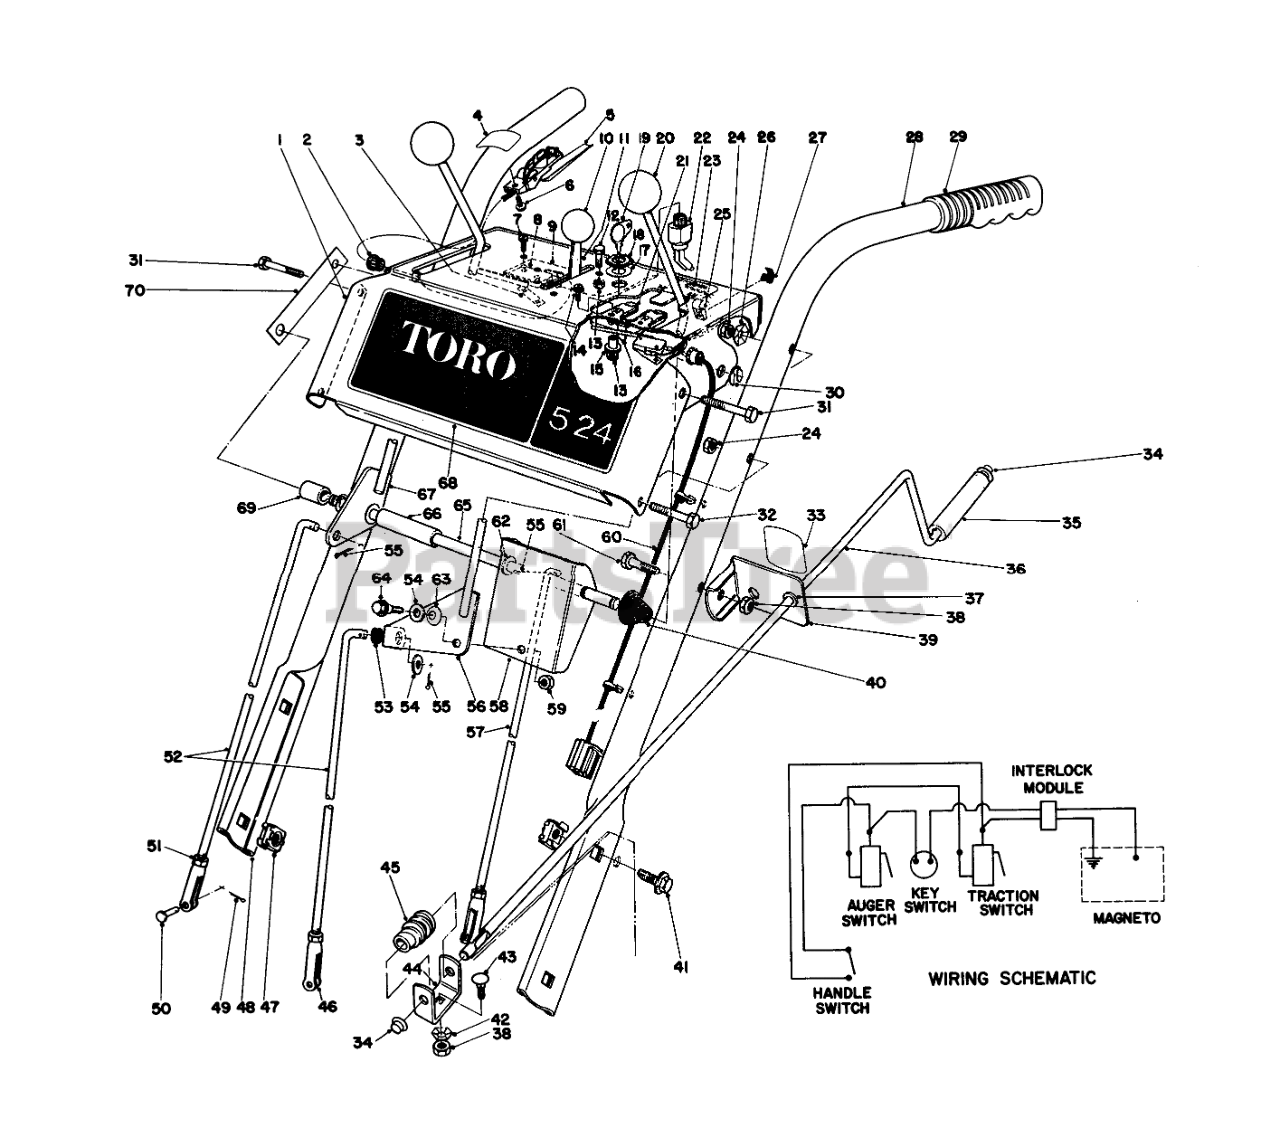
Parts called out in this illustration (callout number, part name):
1	ESCUTCHEON PLT B
2	BUSHING NYLON
3	NUT-SPEED
4	INTERLOCK DECAL
5	INTERLOCK HDLE SWITCH
6	SCREW
7	SCREW-SPH
8	SWITCH-MICRO
9	SWITCH MTG PAD
10	CONTROL KNOB
11	THROTTLE CONTROL
12	HEX HEAD SEMS 10-24X1/2
13	NUT-LOCK, NI
14	SCREW-SRH
15	INTERLOCK SPACER
16	INTERLOCK SPRING
17	WASHER-TOOTH, INTERNAL
18	NUT-HH
19	Key
21	Slide Interlock
22	Key Switch
23	INSTR DECAL
24	NUT-LOCK, CONE
25	WIRE CLAMP
26	Washer
27	Mounting Stud
28	LEFT HANDLE
29	Grip Handle
30	RING-CLIP
31	SCREW-HH
32	SCREW-HH
33	CHUTE DECAL
34	RETAINER-PUSH ON
35	GRIP-CONTROL, CHUTE
36	CHUTE CONTROL ROD
37	Bushing
38	NUT-LOCK, NI
39	Chute Control Rod Mounting (Incl. Ref. #33 & 37)
40	CONICAL SPRING
41	SCREW-HHF
42	WASHER-LOCK
43	BOLT-CARR
44	BRACKET-WORM
45	GEAR-WORM, CHUTE
46	CLEVIS
47	Retained Nut
48	HANDLE RIGHT
49	PIN-COTTER
50	PIN-CLEVIS
51	NUT-HJ
52	SPEED SELECTOR ROD
53	GROMMET-RUBBER
54	WASHER-FLAT
55	PIN-COTTER
56	SHIFT LEVER WA
57	TRACTION CONTROL ROD
58	SHIFT BRACKET
59	NUT-LOCK, CONE
60	Wire Harness-Interlock
61	SCREW-HH
62	WASHER-FLAT
63	7/16 SPRING WASHER
64	SHOULDER SCREW
65	PIVOT ROD
66	SHIFT LEVER SPACER
67	LEVER WA
68	ESCUTCHEON DECAL
69	AUGER LEVER SPACER
70	ESCUTCHEON SUPT STRAP
